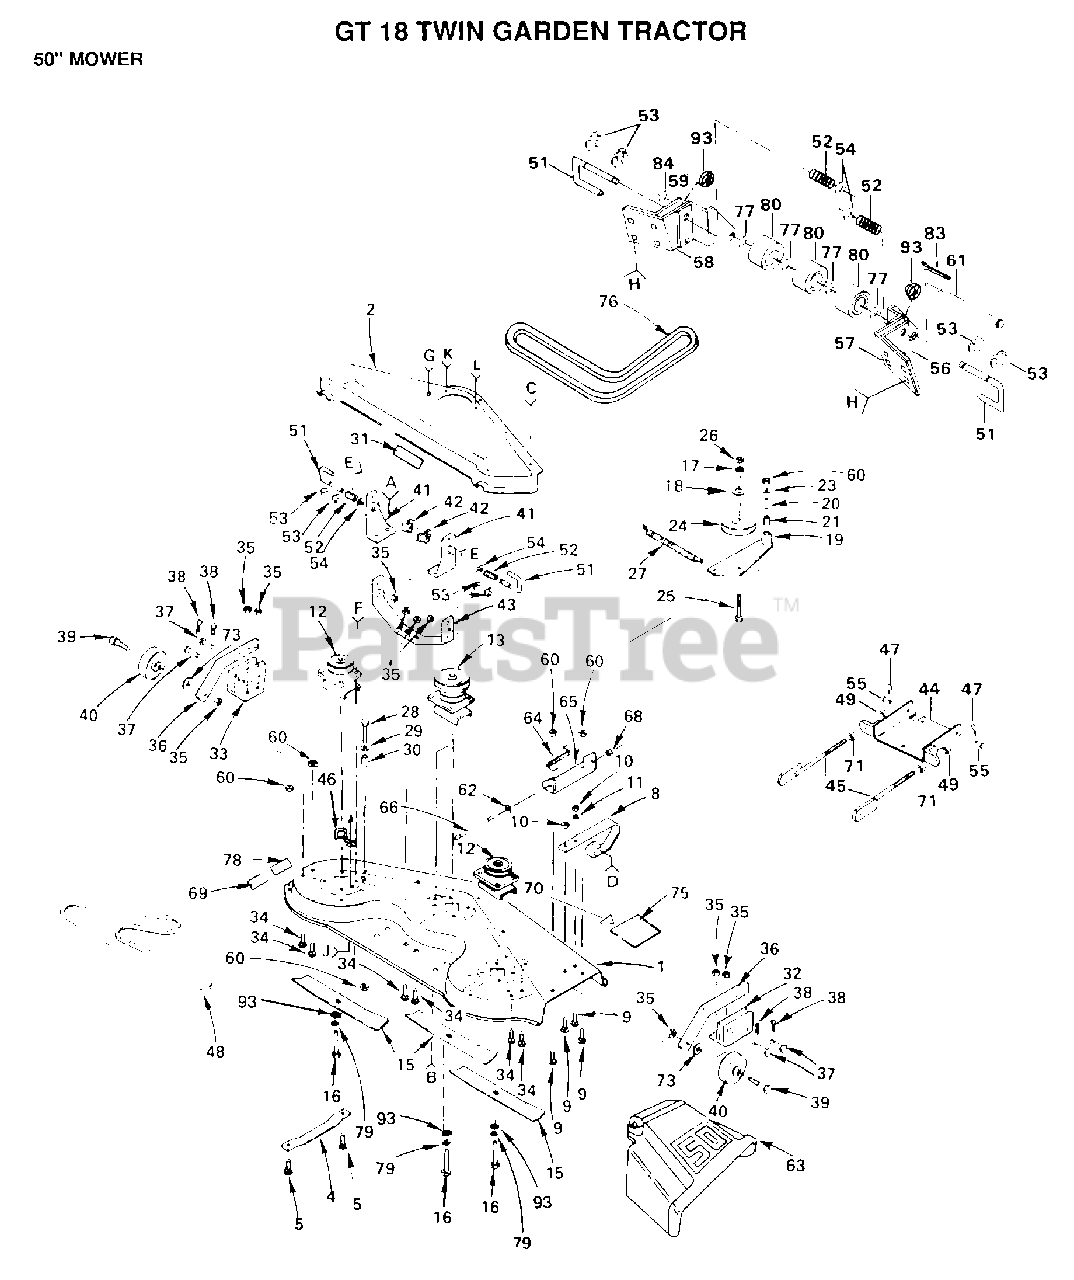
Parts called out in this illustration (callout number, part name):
4	RUNNER-LH M
5	BOLT
9	BOLT
11	WASHER
15	"BLADE.50""STD.LIFT"
16	BOLT.3/8-24X1-1/2
17	LOCKWASHER
18	WASHER
19	ARM ASSY GT
23	WASHER
24	IDLER-FLAT T
26	NUT.HEX.3/8-16UNC
27	SPRING T
28	BOLT
29	WASHER M
30	SPACER SPLIT LT
32	GUAGE WHL BRKT GT
33	GUAGE WHL BRKT GT
34	BOLT
36	GUAGE WHL BAR GT
39	BOLT M
40	WHEEL.GAGE.BLK.PL
41	SUSP BRKT GT
42	SPACER GT
43	SUSP BRACE GT
45	BRACKET.SUSPEN.AS
46	BELT RETIANER
47	RETAINER.SPRING
48	V-BELT M
49	NUT LTV
51	RELEASE PIN GT
52	SPRING M
53	KLIP RING
55	CLEVIS PIN GT
56	BRACKET T
57	BRACKET T
58	BRACKET T
59	BRACKET T
61	PIVOT PIN T
62	WASHER
63	DEFLECTOR
66	ROD-HINGE T
68	NUT PUSH M
69	DECAL INSTRUCTION CAUTION
71	NUT
73	WASHER
75	DECAL WARNING
77	WASHER T
78	DECAL-INST YT
80	ROLLER T
83	COTTER PIN
